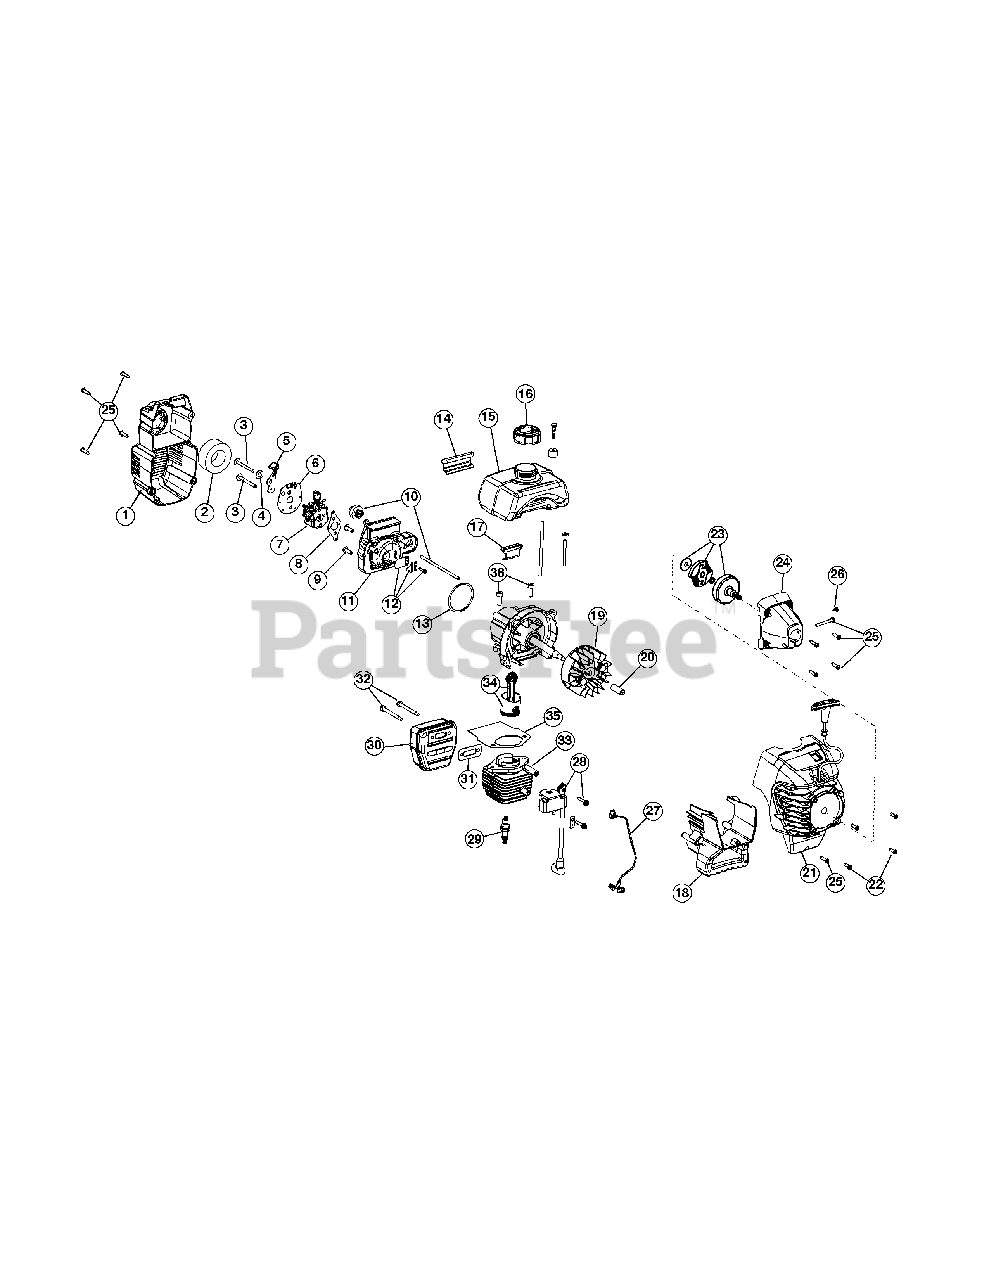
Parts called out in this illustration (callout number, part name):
1	Air Cleaner Cover Assembly
2	Air Cleaner Filter
3	Carburetor Mounting Screw Assembly
4	Wavey Washer
5	Choke Lever
6	Choke Plate
7	Carburetor Assembly
8	Carburetor Gasket
9	Carb Mount Screw
10	Primer & Hose Assembly
11	Carb Mount Assembly
12	Reed Assembly
13	Carburetor O-Ring
14	Rear Mounting Pad
15	Fuel Tank Assembly
16	Fuel Cap Assembly
17	Front Mounting Pad
18	Shroud Extension & Stand
19	Flywheel Assembly
21	Starter Housing Assembly
22	Housing Screw
23	Clutch Rotor Assembly
24	Clutch Cover Assembly
25	Cover Screw
26	Anti-Rotation Screw
27	Wire Leads and Sleeve
28	Module Assembly
30	Muffler Assembly
31	Exhaust Gasket
32	Muffler Mounting Bolts
33	Cylinder Assembly
34	Piston and Rod Assembly
35	Cylinder Gasket
36	Cylinder Bolt
